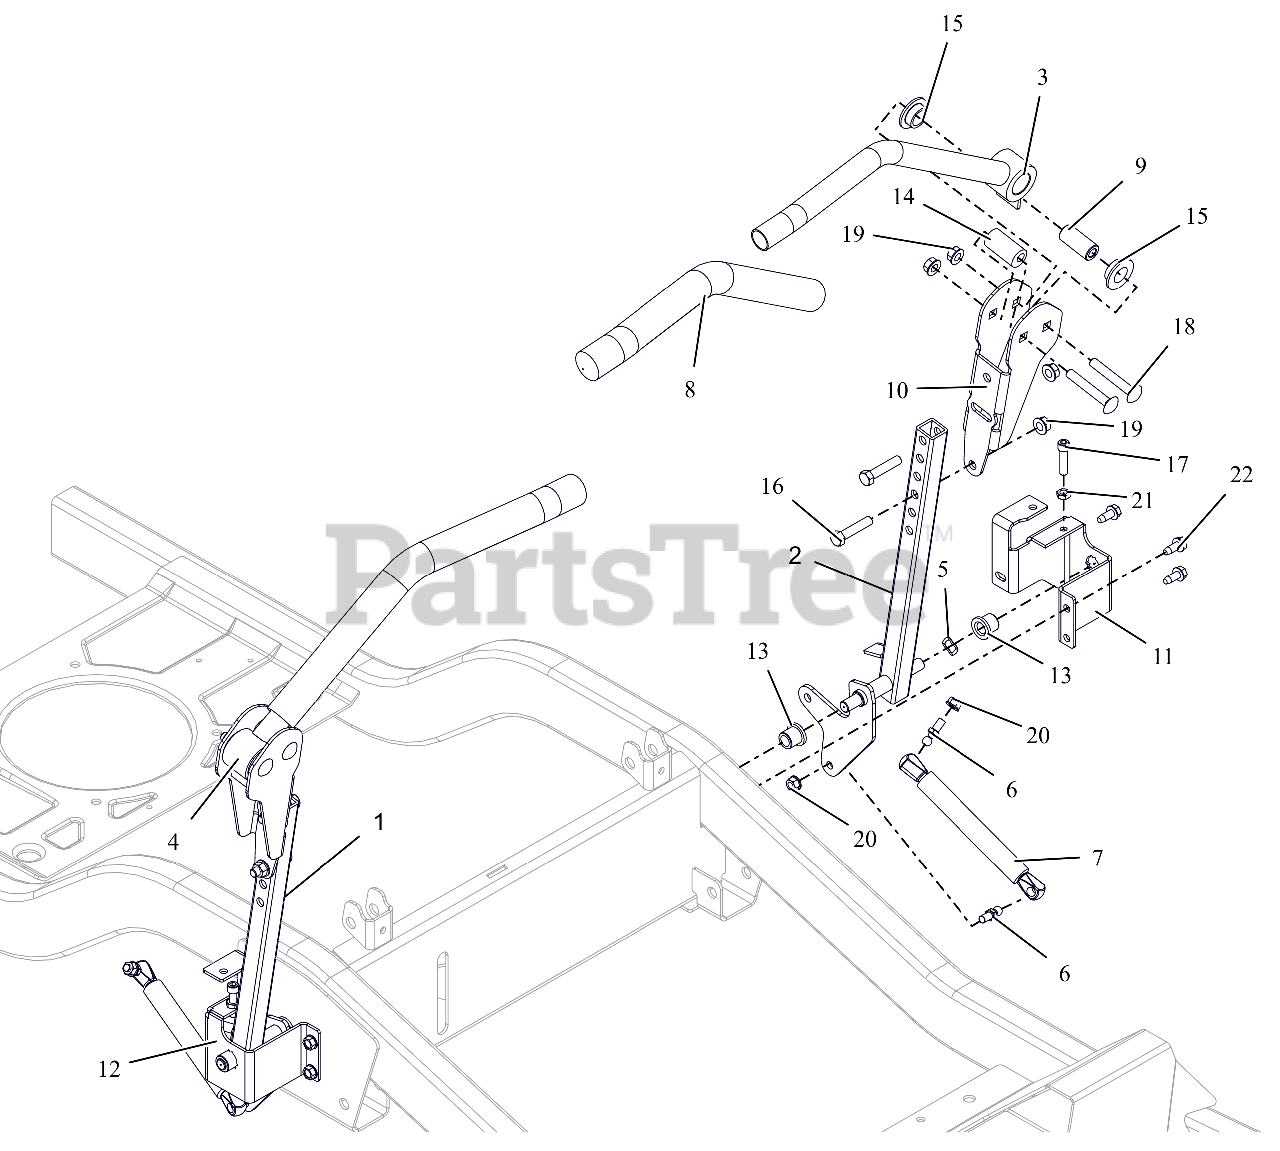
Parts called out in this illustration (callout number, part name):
1	WLDMT, STEERING RH (BLACK)
2	WLDMT, STEERING -LH (BLACK)
3	WLDMT, CONTROL HANDLE- BLK
4	WLDMT, CONTROL HANDLE- BLK
5	WAVE WASHER .531X.781X.125FH
6	STUD- BALL
7	DAMPER
8	GRIP, HANDLEBAR
9	SPACER, STEERING ARM
10	ADJ UPPER CONTROL ARM BRKT-BLK
11	BRKT, STEERING ARM MOUNT -LH
12	BRKT, STEERING ARM MOUNT -RH
13	BHSG-FLG .500X.750X.750X.125
14	BSHG, ECCENTRIC.406X.875X1.625
15	BSHG-FLG .762X1.48X.44 NYL
16	BLT, HEX .38-16X1.75 G5 ZCC
17	SCR, SKH .312-18X1.25 GR8 ZC120
18	BLT, RHSSN.38-16X2.50 G5 ZCC
19	NUT-LK-TOP-FLG .38-16 ZC120
20	NUT,LK-CTR-FLG .31-18 GF ZCC
21	NUT-JAM .312-18 G2 ZCC
22	SCR,TAP .312-18X.75 HWH TR ZCC
